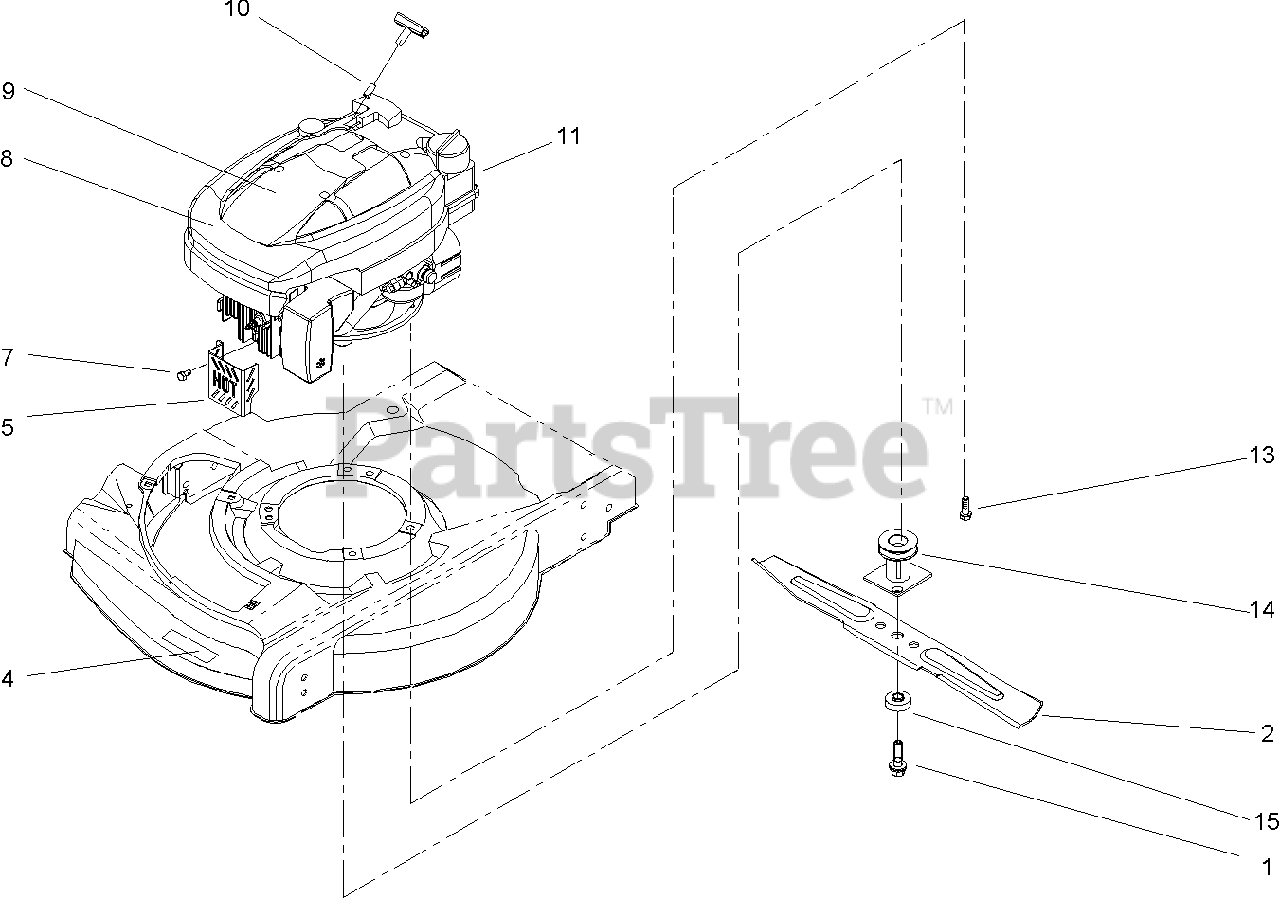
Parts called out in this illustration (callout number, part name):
1	BOLT-BLADE
4	DECAL-DECK
5	GUARD-MUFFLER
7	SCREW-HWH
8	APPLIQUE
9	DECAL-RECOIL
10	STOP-ROPE
13	SCREW-TAPTITE
14	DRIVER-BLADE
